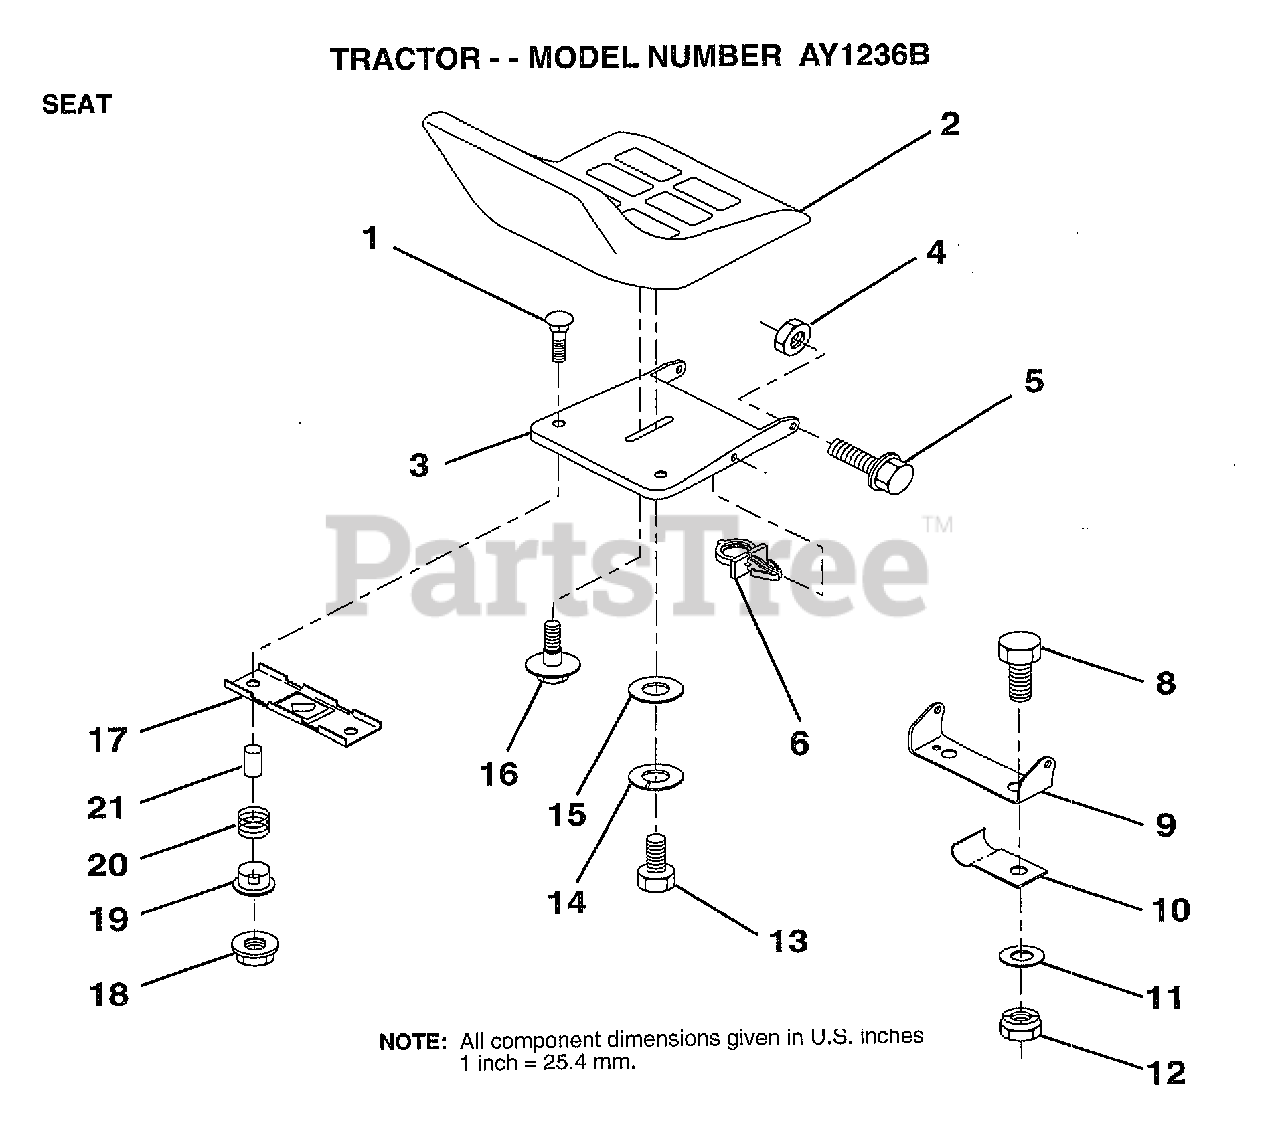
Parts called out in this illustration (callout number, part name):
4	NUT
5	"BOLT,SHOULDER"
6	CLIP.PUSH-IN.HING
8	BOLT
9	BRACKET PVT SEAT
10	"CLIP,INSULATOR"
11	WASHER
12	NUT
13	BOLT
14	LOCKWASHER
15	WASHER
16	"BOLT,SHOULDER"
17	BRKT SWITCH
19	BUSHING
20	SPRING
21	SPLIT SPACER
